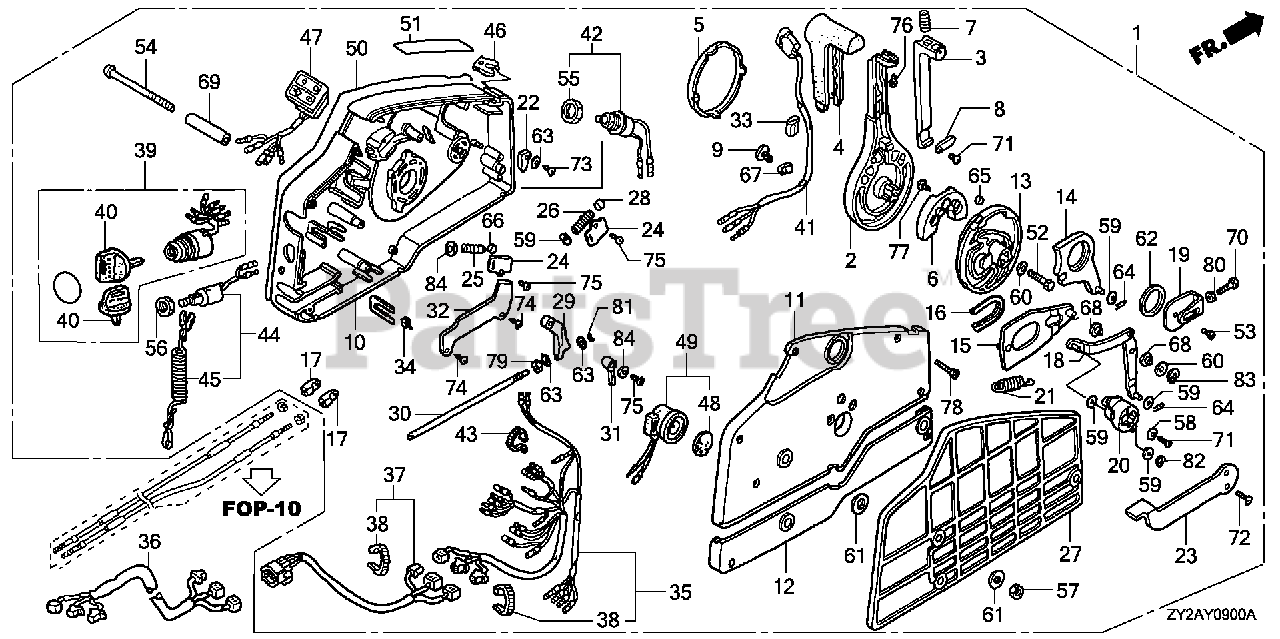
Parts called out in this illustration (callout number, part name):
1	S/R SW 2 LIGH POW TL
1	BOX ASSY., REMOTE CONTROL (P/T)
1	BOX ASSY., REMOTE CONTROL (P/T)(HI-LEX)
2	HANDLE, REMOTE CONTROL
3	LEVER, HANDLE LOCK
4	GRIP, REMOTE CONTROL HANDLE
5	CAP, HANDLE
6	BLOCK, NEUTRAL LOCK
7	SPRING, REMOTE CONTROL HANDLE
8	PLATE, LEVER SETTING
9	CLAMP, HARNESS
10	HOUSING, REMOTE CONTROL BOX (A)
11	HOUSING, REMOTE CONTROL BOX (B)
12	HOUSING, REMOTE CONTROL BOX (C)
13	WHEEL, CONTROL
14	ARM, SHIFT LINK
15	PLATE, SLIDING
16	COLLAR, SLIDING PLATE
17	PIVOT, SHIFT
18	ARM, LINK JOINT
19	BRACKET, LINK JOINT
20	WHEEL, ACCELERATOR
21	SPRING, ACCELERATOR WHEEL
22	CAM, STARTER SWITCH
23	LEVER, IDLE
24	PLATE, SPRING SETTING
25	SPRING, SHIFT CLICK
26	SPRING, CHOKE RETURN
27	SPACER, REMOTE CONTROL BOX
28	SPACER, CLICK SPRING
29	BLOCK, THROTTLE FRICTION
30	BOLT, FRICTION
31	SPACER, NEUTRAL SWITCH
32	CLAMP, POWER TILT CORD
33	PIPE, HARNESS GUIDE
34	SPACER, CABLE CLAMP
35	CABLE ASSY., REMOTE CONTROL (B)
36	CABLE ASSY., REMOTE CONTROL EXTENSION
37	CABLE ASSY., SWITCH PANEL
38	TIE, CABLE (2.4X92) (NATURAL)
39	SWITCH ASSY., COMBINATION
40	KEY ASSY., COMBINATION SWITCH (35100-ZV5-003 ONLY)
41	SWITCH ASSY., POWER TRIM-TILT
42	SWITCH ASSY., SOLENOID
43	BAND (BLACK 3.5X140)
44	SWITCH ASSY., EMERGENCY STOP
45	WIRE, EMERGENCY
46	CLIP, EMERGENCY LOCK
47	LAMP ASSY., INDICATION (2-LED)
48	PLATE, TURN SIGNAL BUZZER
49	BUZZER, WARNING
50	PLATE, REMOTE CONTROL (CAUTION PICT=SILVER)
51	MARK, FAST IDLE
52	BOLT, HEX. (8X35)
53	SCREW, PAN (6X10)
54	SCREW (6X95)
55	NUT, HEX. (20MM)
56	NUT, HEX. (16MM)
57	NUT, HEX. (6MM)
58	WASHER, PLAIN (5MM)
59	WASHER, PLAIN (6MM)
60	WASHER, PLAIN (8MM)
61	WASHER (6MM)
62	WASHER (28MM)
63	WASHER, PLAIN (4MM)
64	PIN, LOCK (6MM)
65	PIN (6X6)
66	ROLLER, CLICK
67	CLIP, WIRE HARNESS (6.3MM)
68	COLLAR, LINK JOINT
69	COLLAR, DISTANCE (6X10X43.5)
70	BOLT, HEX. (5X16)
71	SCREW, PAN (5X10)
72	SCREW, OVAL (5X12)
73	SCREW, TAPPING (4X10)
74	SCREW, TAPPING (5X8)
75	SCREW, TAPPING (5X10)
76	SCREW, TAPPING (5X12)
77	SCREW, TAPPING (6X16)
78	SCREW, TAPPING (5X25)
79	NUT, HEX. (6MM)
80	NUT, HEX. (5MM)
81	E-RING (3MM)
82	E-RING (4MM)
83	E-RING (7MM)
